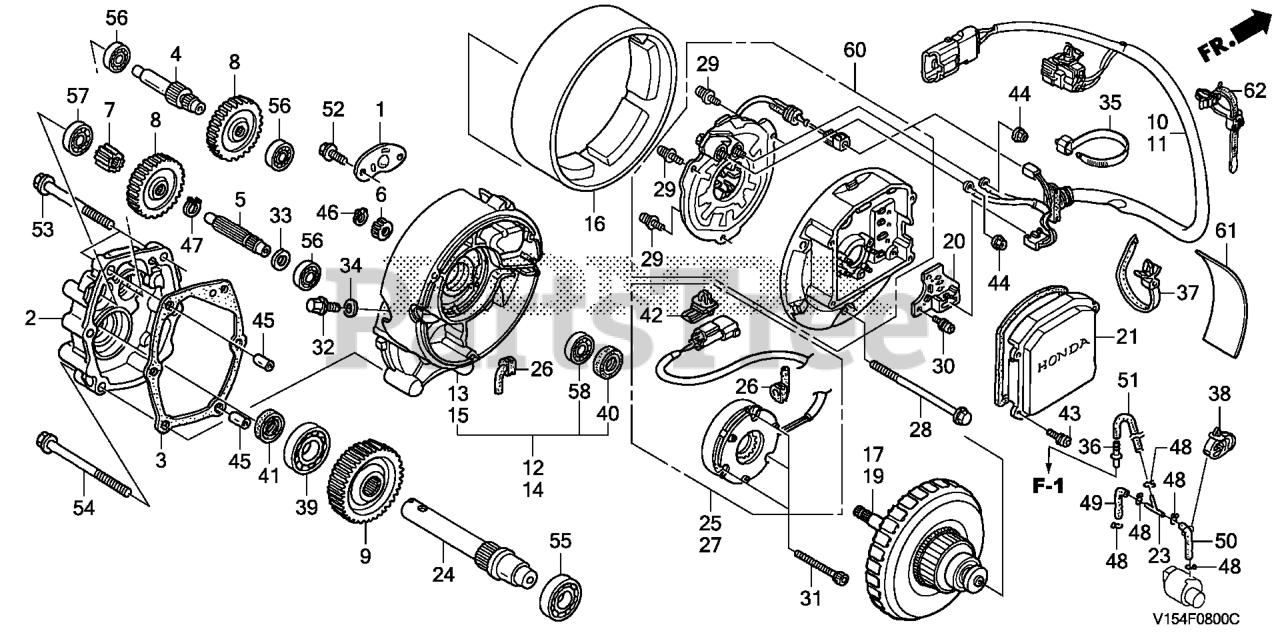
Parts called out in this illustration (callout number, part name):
1	CAP, BREATHER CHAMBER
2	CASE, REDUCTION
3	GASKET, TRANSMISSION CASE
4	COUNTERSHAFT
5	SHAFT, IDLER
6	GEAR, PRIMARY DRIVE (12T)
7	GEAR, FINAL DRIVE (11T)
8	GEAR, PRIMARY DRIVEN (47T)
9	GEAR, FINAL DRIVEN (44T)
10	HARNESS ASSY., R. MOTOR JOINT
11	HARNESS ASSY., L. MOTOR JOINT
12	CASE, R. FR. MOTOR
13	CASE, R. FR. MOTOR
14	CASE, L. FR. MOTOR
15	CASE, L. FR. MOTOR
17	ARMATURE, R.
19	ARMATURE, L.
20	CONTROL UNIT
21	COVER, CONTROL UNIT
23	JOINT Y, TUBE (MITSUBA)
24	SHAFT, WHEEL
25	BRAKE ASSY., R.
26	GROMMET, BRAKE CORD
27	BRAKE ASSY., L.
28	BOLT, FLANGE (6X70)
29	SCREW-WASHER
30	SCREW-WASHER (3X6)
31	BOLT, SOCKET (5X25)
32	BOLT, DRAIN PLUG
33	WASHER (10MM)
34	WASHER, DRAIN PLUG (10.2MM)
35	BAND, WIRE (95MM)
36	JOINT, BREATHER TUBE
37	STRAP, CABLE (105MM) *NH1* (Honda Code 1685536). (BLACK)
38	CLIP, WIRE HARNESS (25MM)
39	BEARING, RADIAL BALL (6205)
40	OIL SEAL (17X35X8)
41	OIL SEAL (25X38X7) (ARAI)
42	CLIP, CONNECTOR (DARK GREEN)
43	SCREW-WASHER (4X10)
44	NUT, FLANGE (5MM)
45	PIN A, DOWEL (10X16)
46	CIRCLIP (OUTER) (10MM)
47	CIRCLIP (OUTER) (12MM) Use up to Engine SN 2056819.
48	CLIP, TUBE (B8)
49	BULK HOSE, VACUUM (3.5X1000) (3.5X500) (BULK HOSE 95005-35008-10M)
50	BULK HOSE, VACUUM (3.5X1000) (3.5X500) (BULK HOSE 95005-35008-10M)
51	BULK HOSE, VACUUM (3.5X1000) (3.5X500) (BULK HOSE 95005-35008-10M)
52	BOLT, FLANGE (6X12) Use up to Engine SN 1543277.
53	BOLT, FLANGE (8X50)
54	BOLT, FLANGE (8X65)
55	BEARING, RADIAL BALL (6004)
56	BEARING, RADIAL BALL (6200)
57	BEARING, RADIAL BALL (6301) (NOT AVAILABLE)
58	BEARING, RADIAL BALL (6201ZZ)
60	COVER, RR. STATOR
61	CUSHION, WIRE HARNESS (50X100)
